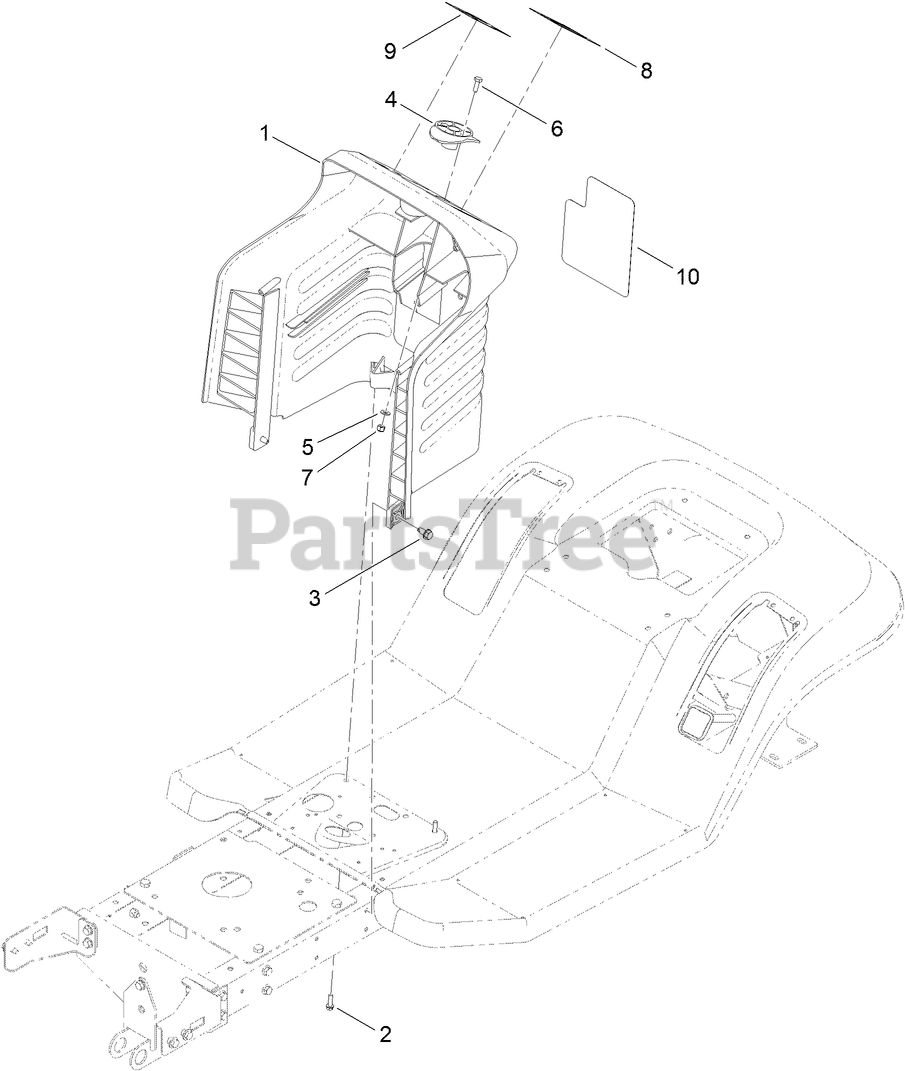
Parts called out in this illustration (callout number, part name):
1	TOWER-STEERING
2	SCREW-HWH
3	SCREW-HWH
4	BUSHING-SLIDING
5	WASHER-FLAT
6	SCREW-HH
7	NUT-LOCK, NI
8	DECAL-THROTTLE/CHOKE
9	DECAL-IGNITION/LIGHTS
10	DECAL-WARNING, INSTRUCTION
